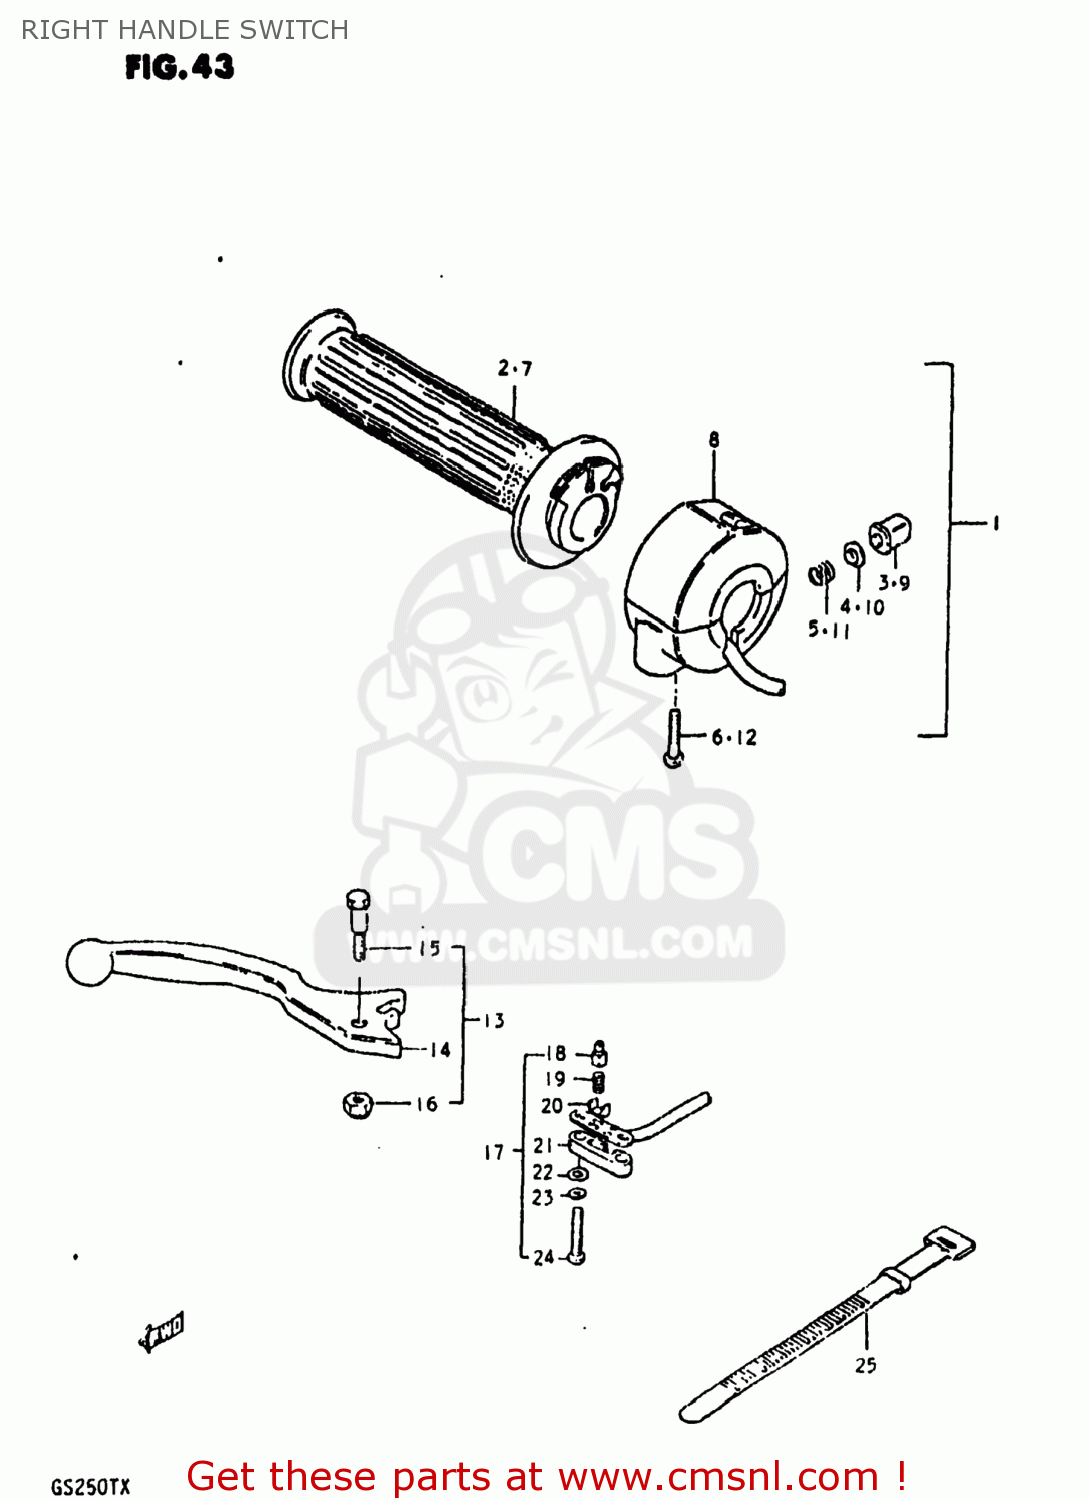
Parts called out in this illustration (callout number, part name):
1	CASE ASSEMBLY,THROTTLE
2	GRIP,THROTTLE
3	BUTTON,HORN
4	CONTACT
5	SPRING
6	SCREW
7	GRIP,THROTTLE
8	CASE ASSEMBLY,THROTTLE
9	BUTTON,HORN
10	CONTACT
11	SPRING
12	SCREW
13	LEVER ASSEMBLY,BRAKE
14	LEVER,BRAKE
15	BOLT
16	NUT 6MM
17	SWITCH ASSEMBLY
18	HOLDER
19	SPRING
20	PLATE
21	COVER,FR BK TERMINAL BASE
22	SCREW
23	LOCK WASHER
24	WASHER
25	CLAMP(L:120)
